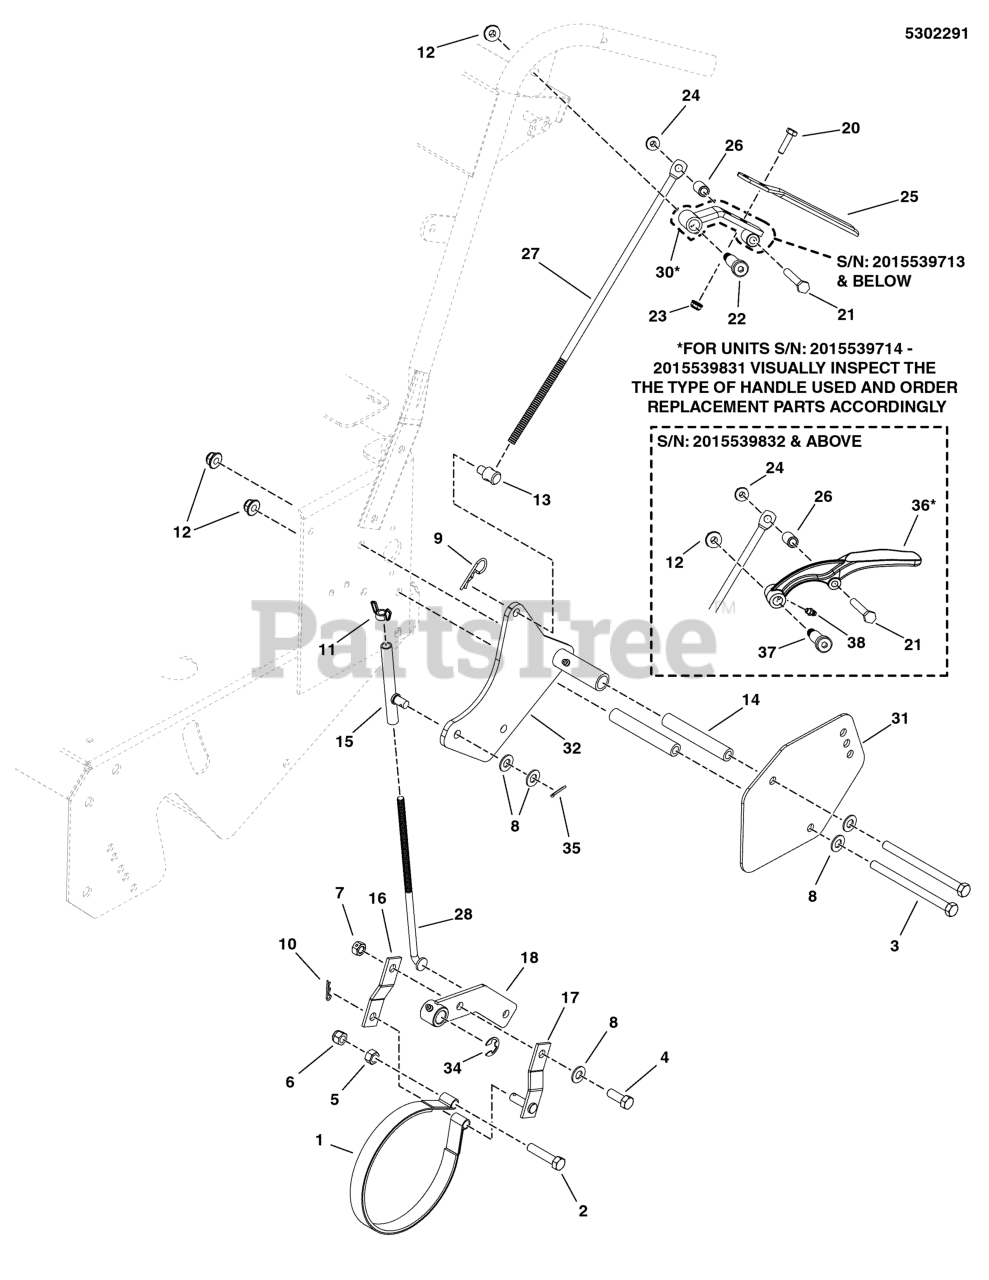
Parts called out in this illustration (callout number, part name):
1	BAND, 6 BRAKE
2	BOLT, 3/8-16 X 1-3/4" GD5 CZ
3	BOLT, 3/8-16 X 5 GD5 YZ
4	BOLT, 3/8-16 X 1" GD5 CZ
5	NUT, 3/8-16 HEX
6	NUT, 3/8-16 HEX NYLON LOCK
7	NUT, 3/8-16 HEX SIDE LOCK
8	WASHER, 3/8 SAE
9	PIN, HAIR, .0915 X 1-7/8
10	PIN, HAIR, .0585 X 1-1/8, 1/4 EYE, YZ
11	NUT, 5/16-18 WING NYLON LOCK
12	NUT, 3/8-16 HEX NYLOCK FLANGE
13	ADJUSTER, BRAKE LINKAGE
14	SPACER, .38 X .63 X 4.00, CZ
15	BRAKE ADJUSTER WELDMENT - RED
16	LINKAGE, BRAKE BAND - RED
17	BRAKE LINKAGE WELDMENT - RED
18	WELD, LEVER, BRAKE BAND, LH - RED
20	BOLT, 1/4-20 X 3/4, GD5
21	BOLT, 5/16-18 X 2-3/4, GD 5, YZ
22	BOLT-3/8-16 x 1-1/2, 1/2 SHOULDER
23	NUT, 1/4-20 HEX NYLOCK FLANGE
24	NUT, 5/16-18 HEX NYLOCK FLANGE
25	SUPPORT, BRAKE HANDLE - BLK
26	SPACER, .33 X .51 X 1.00, CZ
27	ROD, PARKING BRAKE, SW5
28	ROD, BRAKE LINK, SW5
29	*WELD, REVERSE HANDLE - RH - RED
30	*WELD, REVERSE HANDLE - LH - RED
31	GUARD, DRIVE BELT - RED
32	WELD, DRIVE IDLER PIVOT, LH - RED
34	RING, RETAINING, 5/8 SHAFT
35	PIN, 3/32 X 0.750, COT, ZINC/CLEAR
36	*HANDLE, REVERSING - BLK
37	BOLT, 3/8-16 X 1, 1/2 SHOULDER
38	GREASE FITTING, 1/4-28 STRAIGHT
